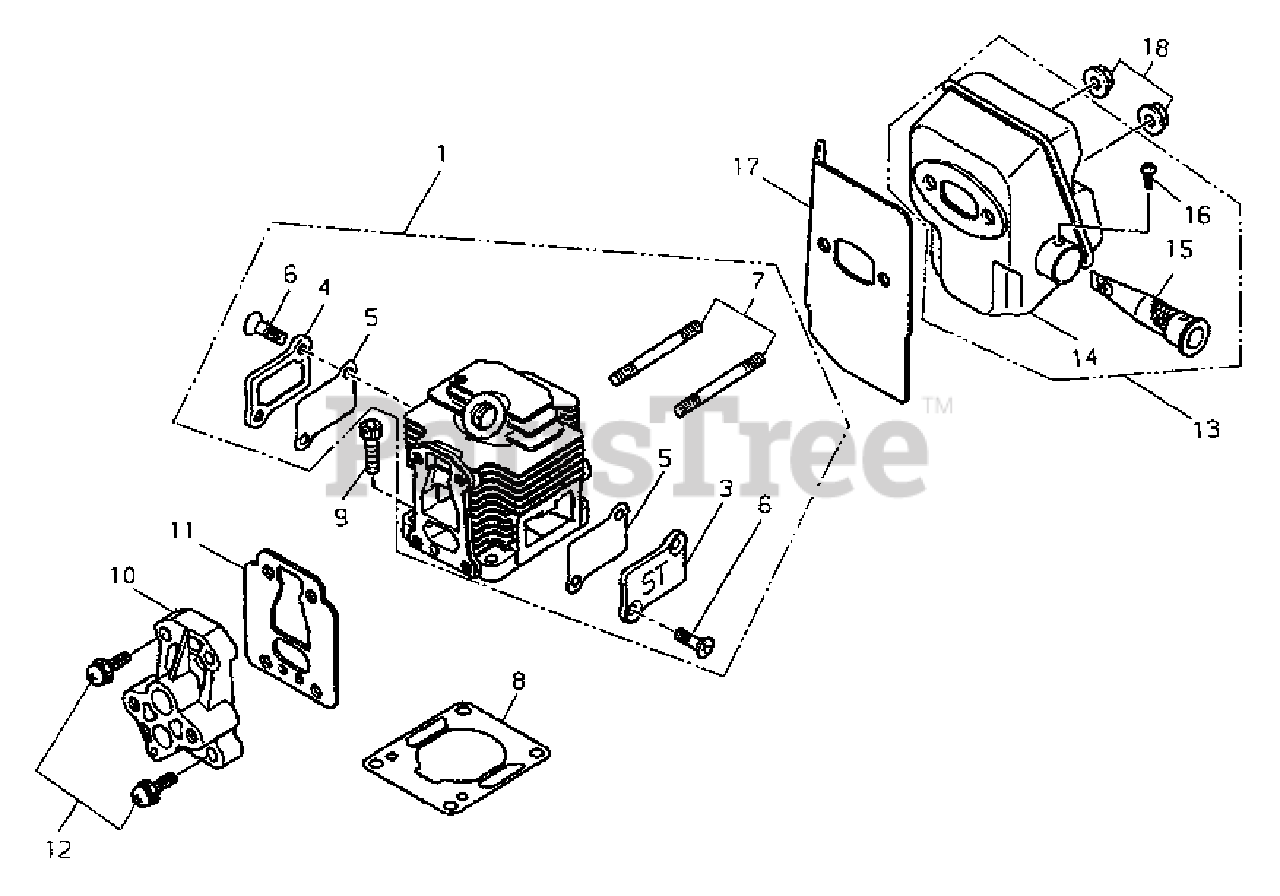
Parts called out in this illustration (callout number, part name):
1	CYLINDER KIT
3	COVER - REAR
4	COVER - FRONT
10	INSULATOR
12	SCREW
13	MUFFLER ASSY
15	SCREEN, SPARK ARRESTER
16	SCREW - TAPPING
17	GASKET
18	NUT - FLANGE
